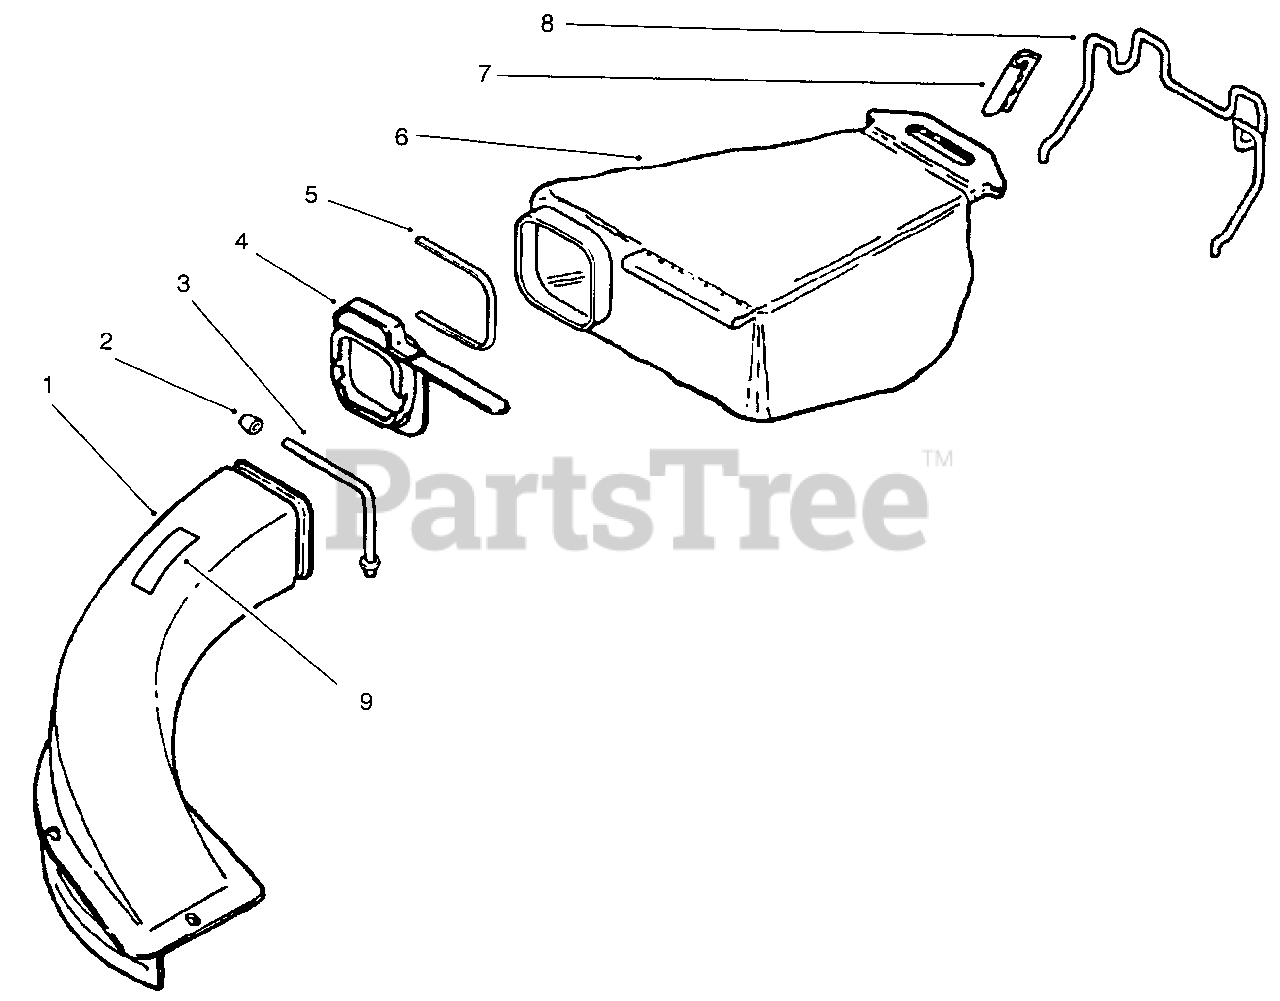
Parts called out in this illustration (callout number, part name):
1	Chute & Support Assy (Incl. Ref. #2, 3 & 9)
2	Nut-Cap
3	Chute Support
4	Adaptor Assembly
5	Tie Strap
6	Bag Assembly (Inc. Ref.#4-5)
7	Hanger Clamp
8	Wide Hanger
9	Decal-Danger
